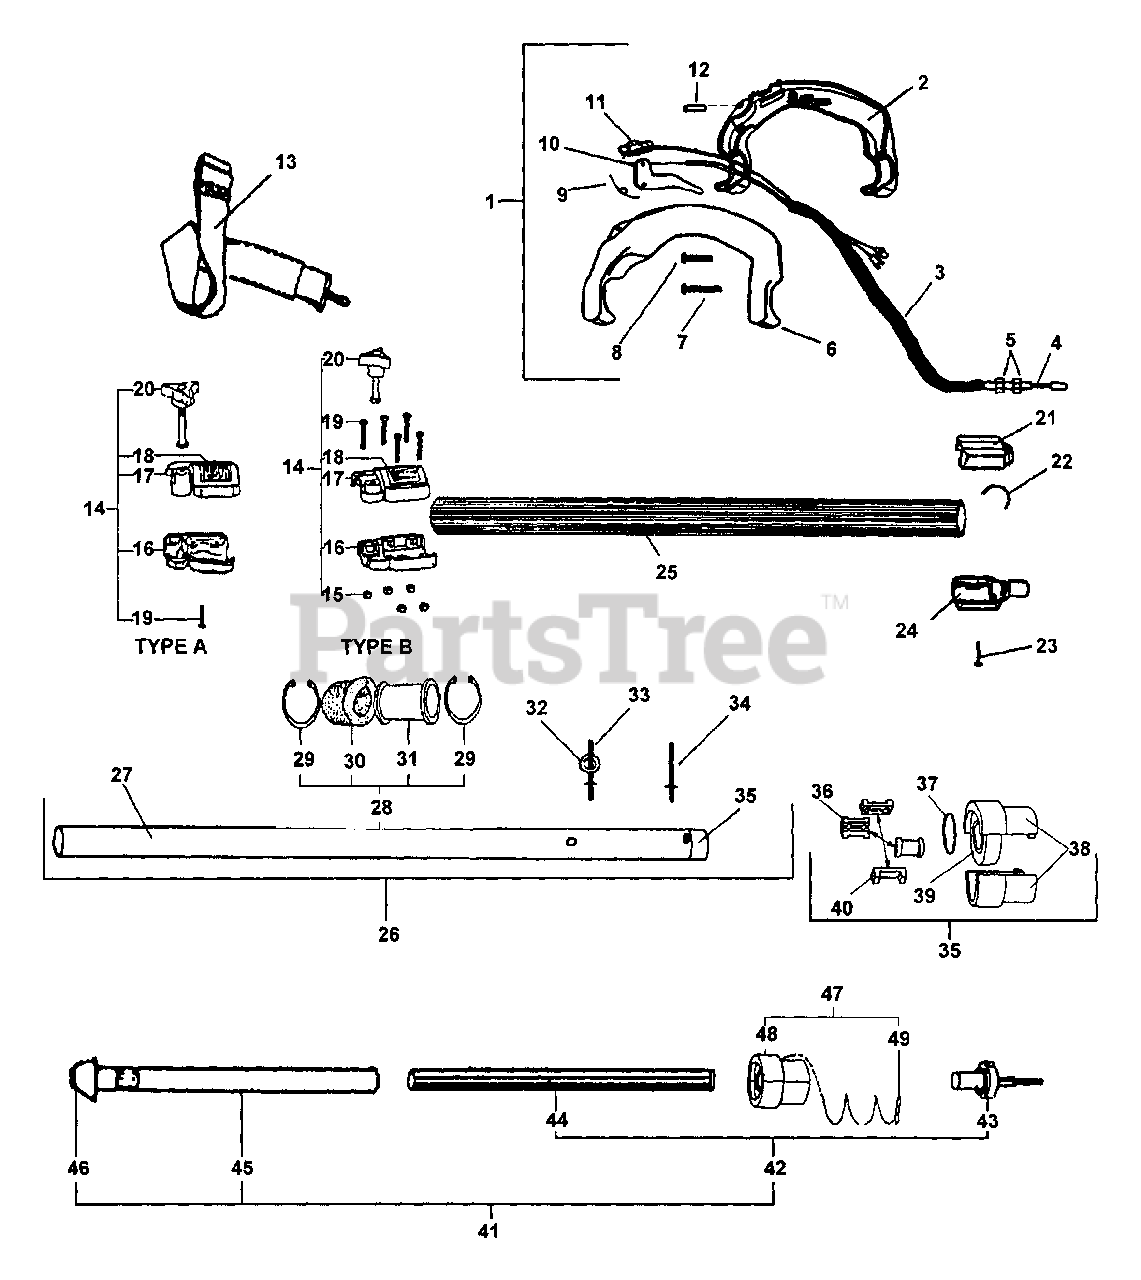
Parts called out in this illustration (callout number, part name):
1	HANDLE ASSY, REAR
2	HANDLE, REAR - RIGHT
3	TUBE, FLEXIBLE
4	CABLE, THROTTLE
6	HANDLE, REAR - LEFT
7	SCREW, TORX 10-24 UNC 1-1/4
8	SCREW, TORX
9	SPRING, TORSION
10	TRIGGER, THROTTLE
11	IGNITION SWITCH ASSY
12	PIN, LOCATING 0.17 OD×0.75 L
13	STRAP ASSY, SHOULDER
14	CLAMP ASSY
15	NUT, LOCK 10-24 UNC
16	COLLAR, LOWER
17	COLLAR, UPPER
18	LABEL - CAUTION
19	SCREW, TORX 10-24 UNC 1-1/4
20	THUMBSCREW
21	CAP, MAIN PIPE
23	SCREW, TORX 10-24 UNC 1-1/4
24	COUPLING, MAIN PIPE
25	PIPE, MAIN 1.5 ID×60" L
26	PIPE, MAIN
27	PIPE, MAIN - BLACK
28	DRIVESHAFT GUIDE ASSY
29	RING, SNAP
30	PAD, FOAM
31	GUIDE, DRIVESHAFT
32	WASHER, FLAT 5
35	HOLDER ASSY, BEARING
36	GUIDE, SHAFT - SMALL
37	WASHER, WAVE
38	HOLDER, BEARING
39	BEARING, BALL 6002 DDU
40	GUIDE, SHAFT - LARGE
41	DRIVESHAFT ASSY
42	DRIVESHAFT - LOWER
43	CONNECTOR, SHAFT
44	DRIVESHAFT
45	DRIVESHAFT
46	ADAPTER, UPPER DRIVE SHAFT
47	BUSHING ASSY, FLOATING
48	SPRING, COMPRESSION
49	BUSHING, FLOATING
